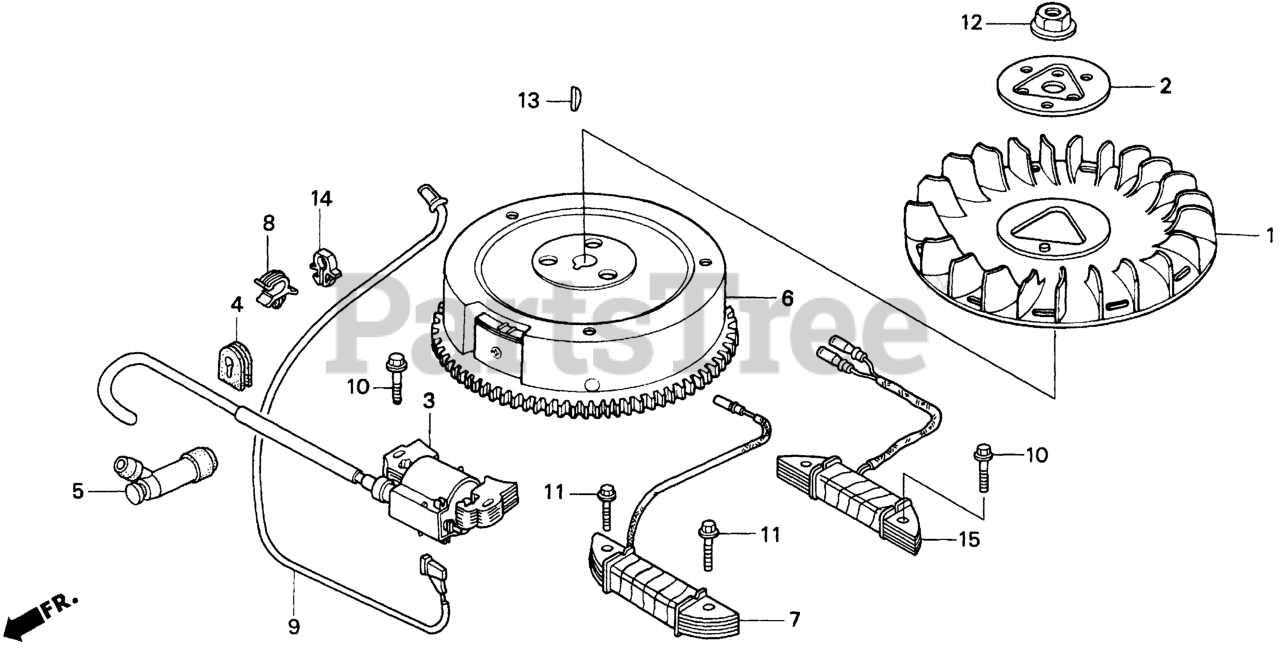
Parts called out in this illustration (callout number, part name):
1	FAN, COOLING
2	PLATE, COOLING FAN SETTING
3	COIL ASSY., IGNITION
4	GROMMET, IGNITION
5	CAP ASSY., NOISE SUPPRESSOR
6	FLYWHEEL COMP. (SEL-4 POLE)
7	COIL ASSY., CHARGE (3A)
8	CLIP, WIRE HARNESS
9	WIRE, STOP SWITCH
10	BOLT, FLANGE (6X28) (CT200) Use up to Engine SN 1530314.
11	BOLT, FLANGE (6X32)
12	NUT, SPECIAL (16MM) (1)
13	KEY, SPECIAL WOODRUFF (25X18)
14	CLIP, HOOD OPEN WIRE
15	COIL ASSY., LAMP (12-34W)
